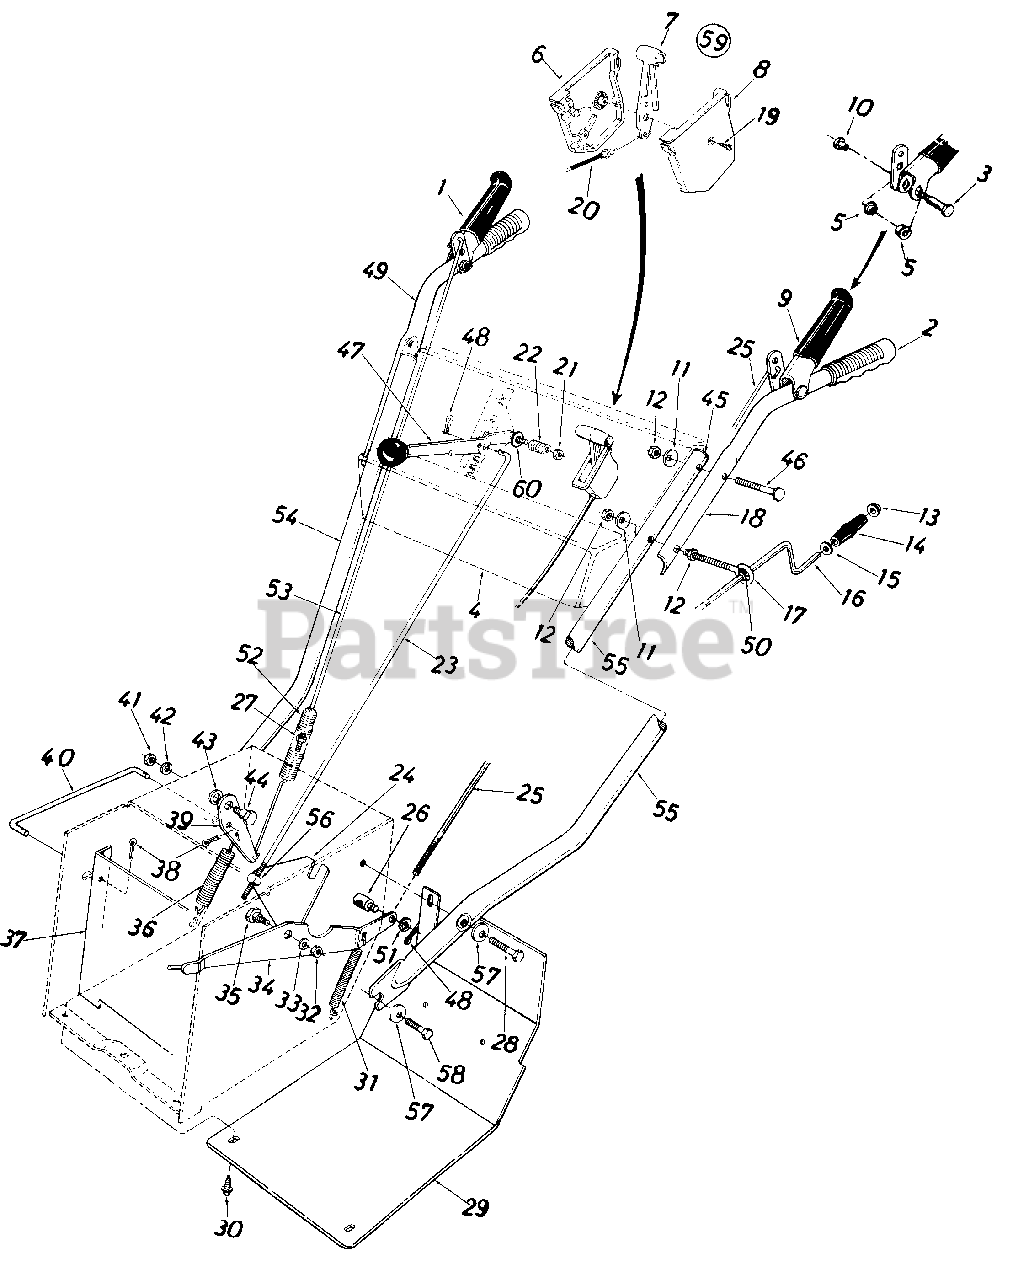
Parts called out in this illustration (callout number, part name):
1	Clutch Grip Ass'y.-R.H.
2	Grip
3	Shoulder Bolt .374 Dia. x 1.53" Lg .
4	Handle Panel Ass'y.
5	Hex Flange Plastic Bearing .380" I.D.
9	Clutch Grip Ass'y.-L.H.
10	Shoulder Nut 1/4-20 Thd.
11	Bell-Wash. .34" I.D. x .88"O.D.
12	Hex Nut 5/16-18 Thd.
13	Push Nut 3/8" Rod
14	Knob 3/8" Rod
15	Fl-Wash. .40" I.D. x .62" O.D.
16	Chute Crank Ass'y.
17	Eye Bolt 5/16-18 x 5.0" Lg.
18	Upper Handle-L.H.
20	Throttle Control Wire
21	Hex Ins. L-Nut 3/8-24 Thd.
22	Compression Spring .50" O.D. x .88" Lg.
23	Shifting Rod 5/16" x 32.50" Lg.
24	Shifting Linkage Bracket
25	Lockout Rod .214" Dia. x 36.0" Lg.
26	Adjustment Ferrule 1/4-20
27	Hex Ins. L-Nut 1/4-20 Thd.
28	Hex Bolt 3/8-16 x 2.00" Lg.
29	Frame Cover
30	Hex Wash. Self-Tap Scr. 1/4-20 x .50" Lg.
31	Extension Spring .38" O.D. x 3.25" Lg.
32	Hex Jam Nut 3/8-16 Thd.
33	L-Wash. 3/8" I.D.
34	Auger Clutch Bracket Ass'y.
35	Shld. Bolt .625" Dia. x .170
36	Extension Spring .75" O.D. x 4.31" Lg.
37	Drive Pulley Support Brkt. Ass'y.
38	Cotter Pin 3132" Dia. x .75" Lg .
39	Drive Clutch Bracket
40	Drive Clutch Rod
41	Hex Jam Nut 3/8-16 Thd.
42	L-Wash. 3/8" I.D.
43	Fl-Wash. .34" I.D. x .75" O.D.
44	Shld. Bolt .625" Dia. x .170
45	Plastic Plug
46	Carriage Bolt 5/16-18 x 2.0" Lg.
47	Shift Handle Ass'y.
48	Int. Cotter Pin 5/16" Dia.
49	Upper Handle-R.H.
50	Grommet
51	Fl-Wash. .28" I.D. x .62" O.D.
52	Extension Spring .75" O.D. x 5.00" Lg.
53	Lockout Rod .214" Dia. x 32" Lg.
54	Lower Handle-R.H.
55	Lower Handle-L.H.
56	Adjustment Ferrule
57	Bell-Wash. .40" I.D. x .88" O.D.
58	Hex Wash. Self-Tap Scr. 3/8-16 x .75" Lg.
59	Throttle Control Box Ass'y.
60	Bell-Wash. .40" I.D. x .88"O.D.
